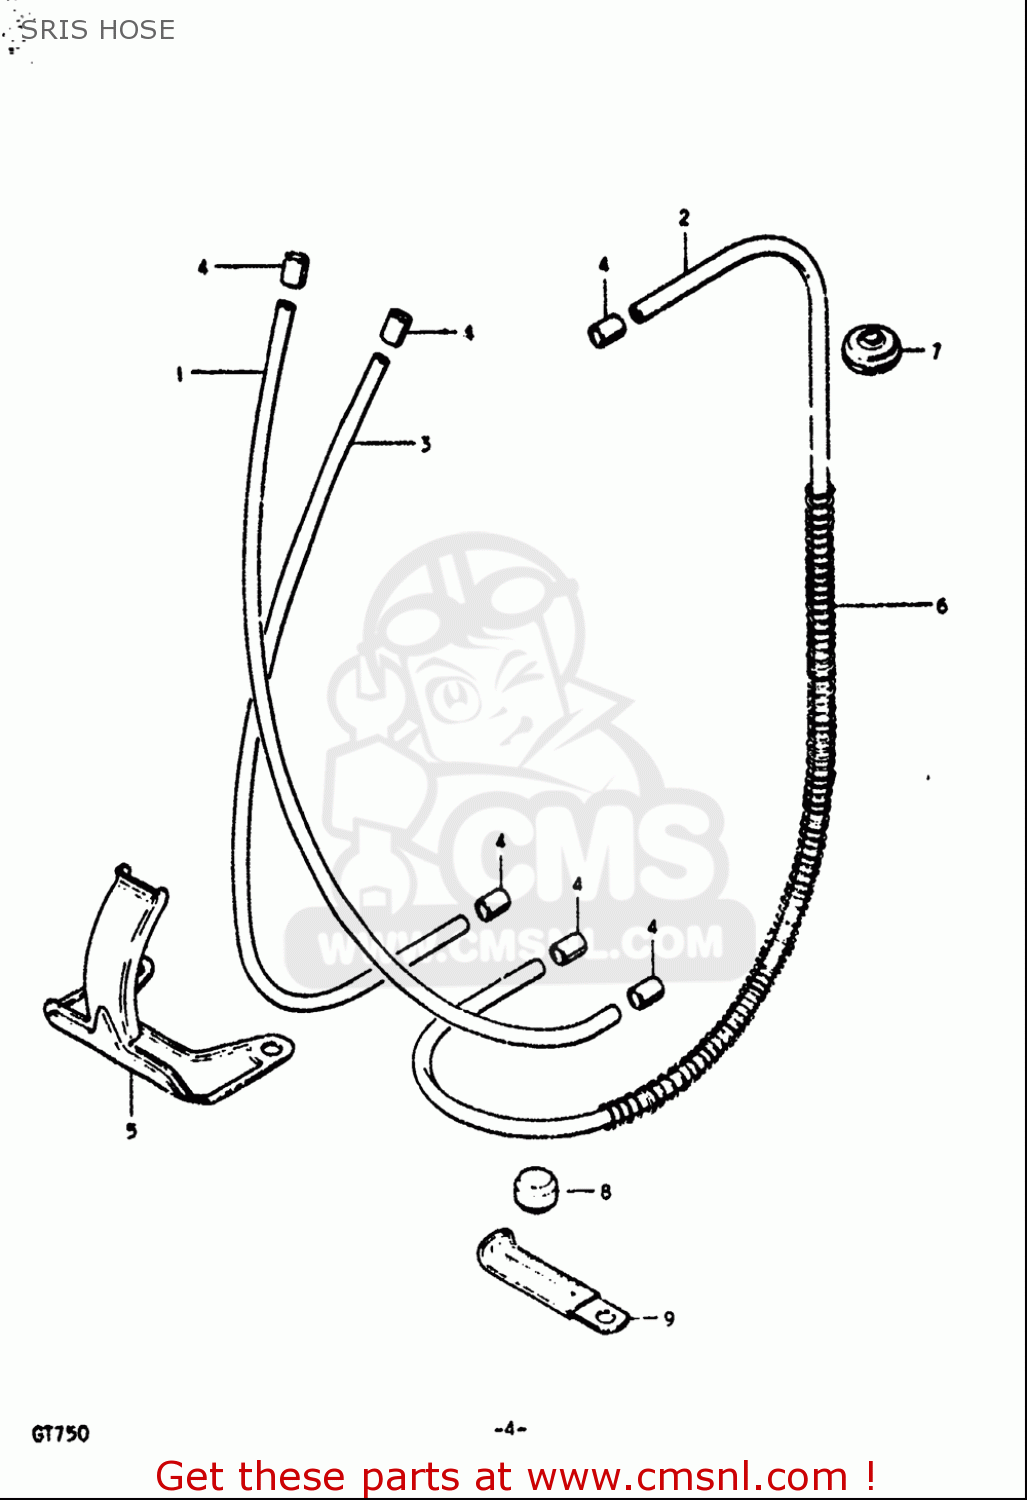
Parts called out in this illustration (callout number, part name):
1	HOSE(2X5X600)
2	HOSE(2X5X600)
3	HOSE(2X5X600)
4	CLIP
7	GROMMET
8	PAD,CYLINDER HEAD
